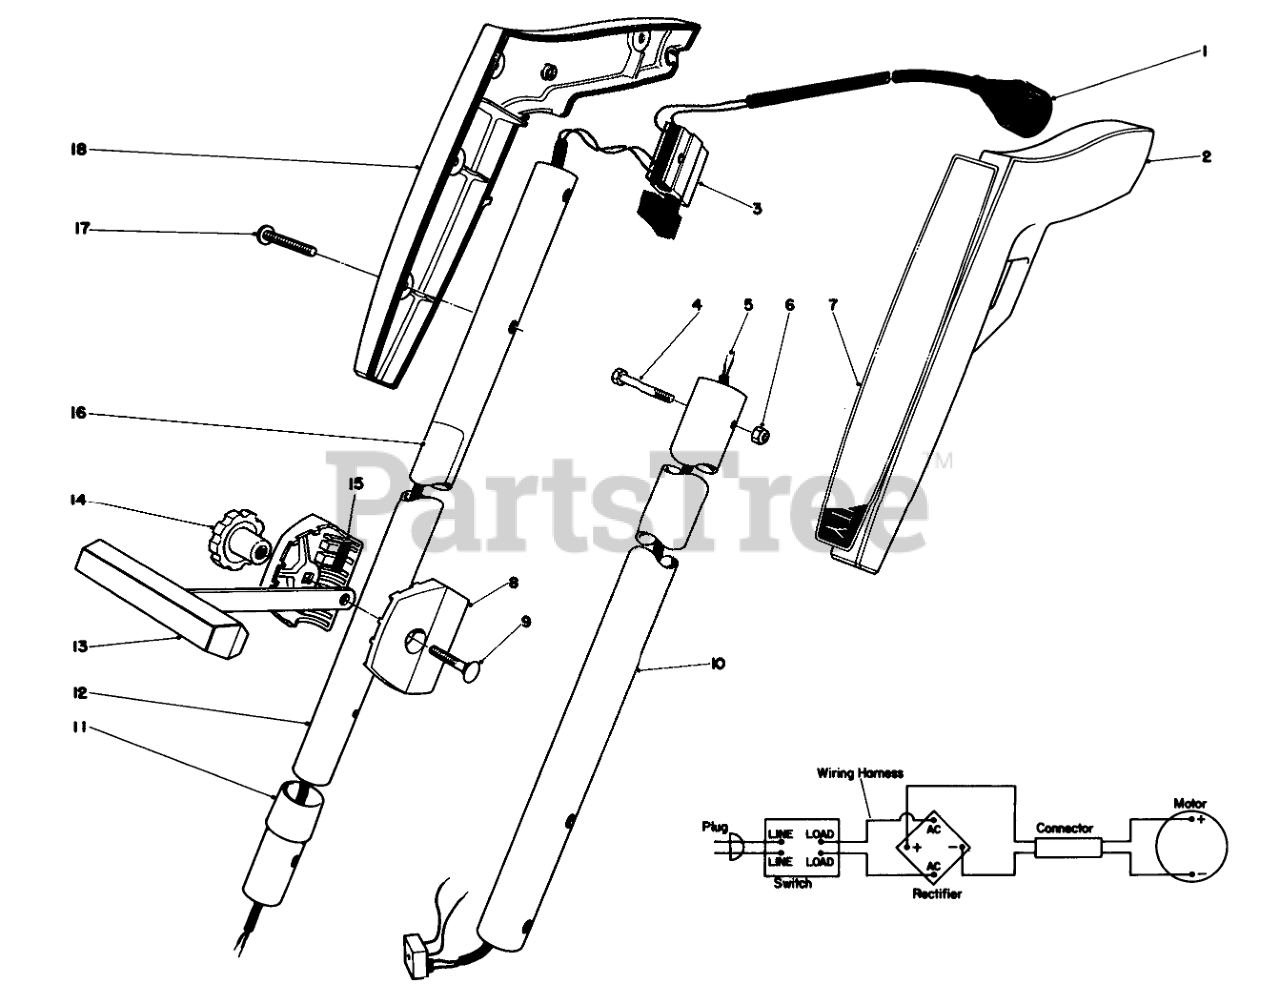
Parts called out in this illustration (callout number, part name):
1	Cord-Power
2	Left Hand Grip
3	SWITCH SINGLE SPEED
4	Screw
5	WIRE HARNESS
6	NUT-LOCK, NI
7	Decal
8	Bracket
9	BOLT-CARR
10	Lower Tube
11	Tubing Sleeve
12	Tube-Upper
13	Tee Handle
15	RUBBER INSERT
16	REP. SERIAL PLT
17	Screw
18	Right Hand Grip
